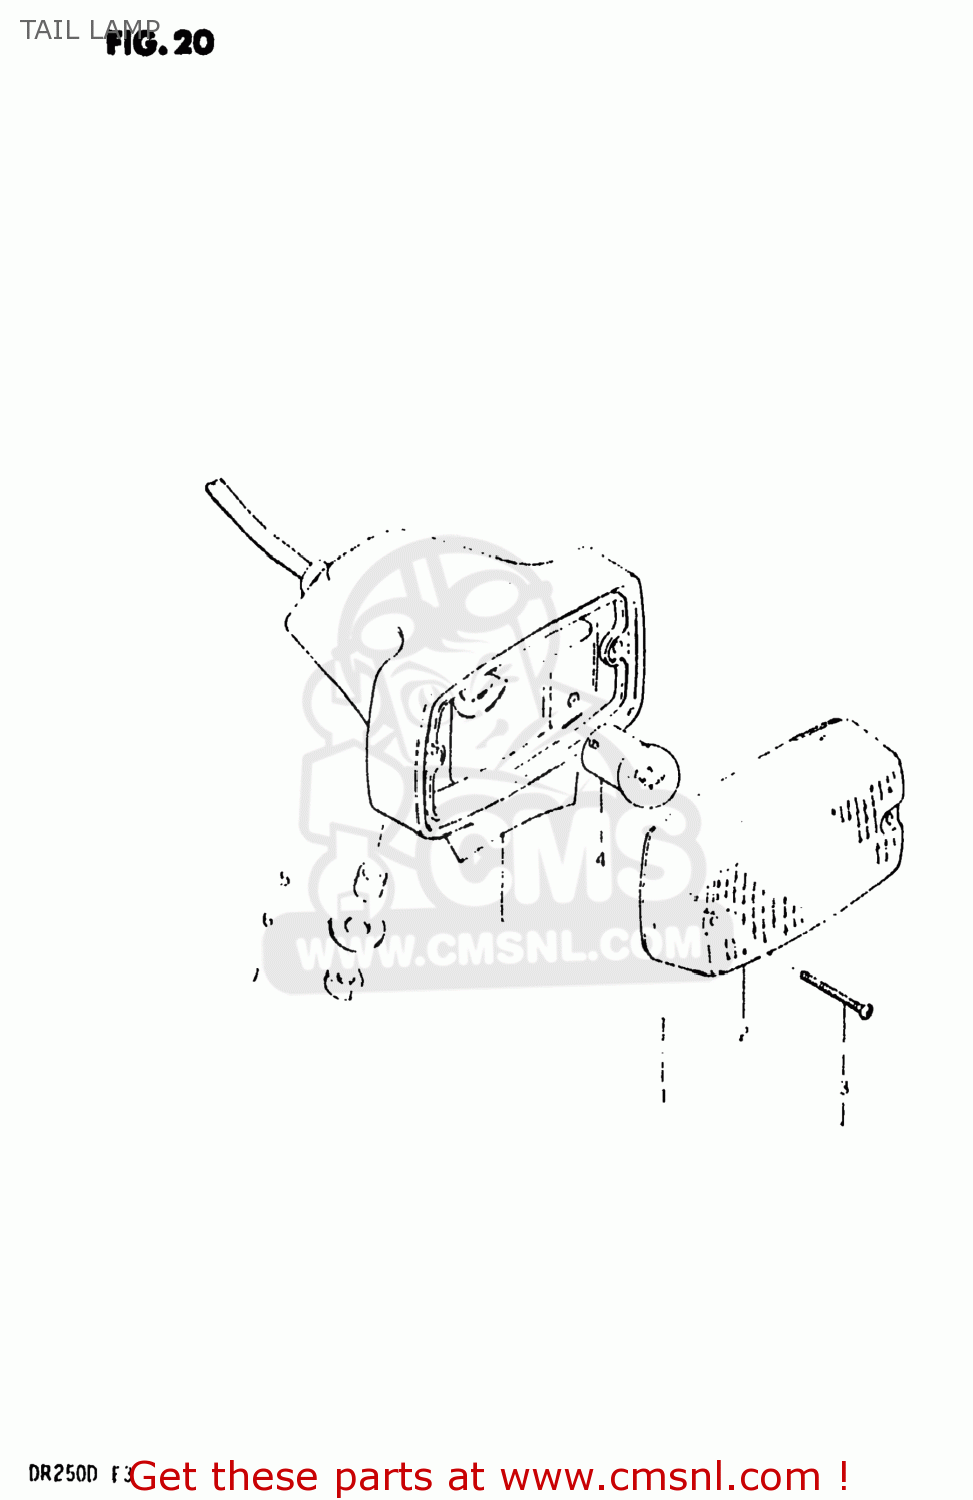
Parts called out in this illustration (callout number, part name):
1	LAMP ASSEMBLY,TAIL
2	LENS
3	SCREW,REAR COMBINATION LAMP LENS
4	BULB(6V5W,TOKAI DENSO)
5	SPACER (6.3X9.1X6.7)
6	WASHER
7	NUT
